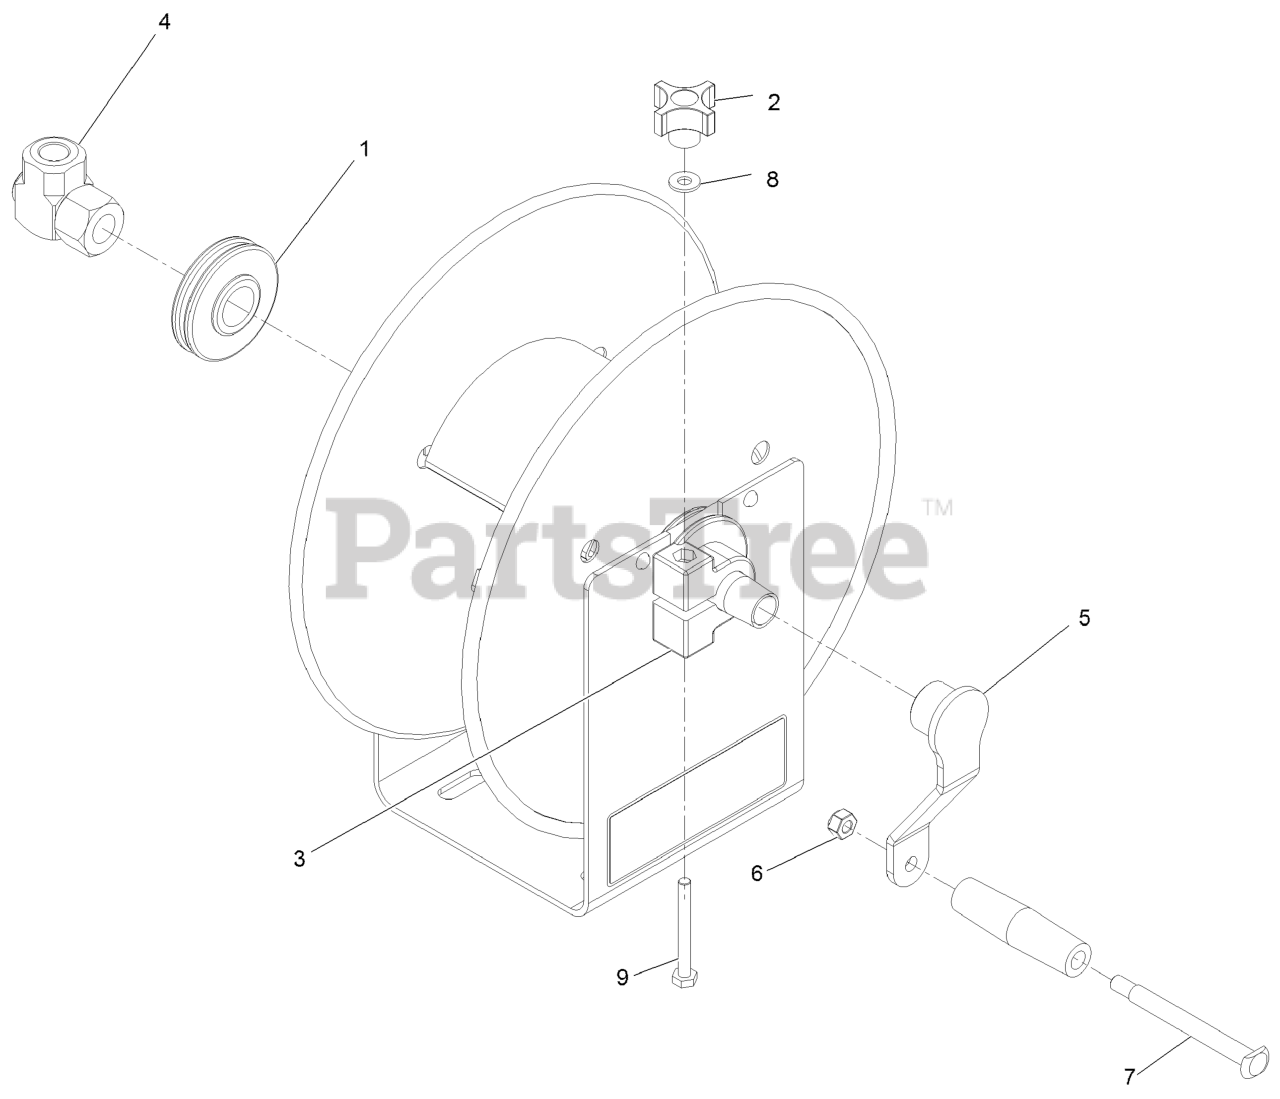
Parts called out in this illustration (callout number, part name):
1	PLASTIC BEARING
2	HOSE REEL BRAKE KNOB
3	BRAKE/BEARING 6329-1-1
4	SWIVEL 3/8" NPT
5	Crank-Reel
6	NUT-HEX
7	BOLT, HOSE REEL HANDLE
8	Washer-Flat
9	SCREW-HH
